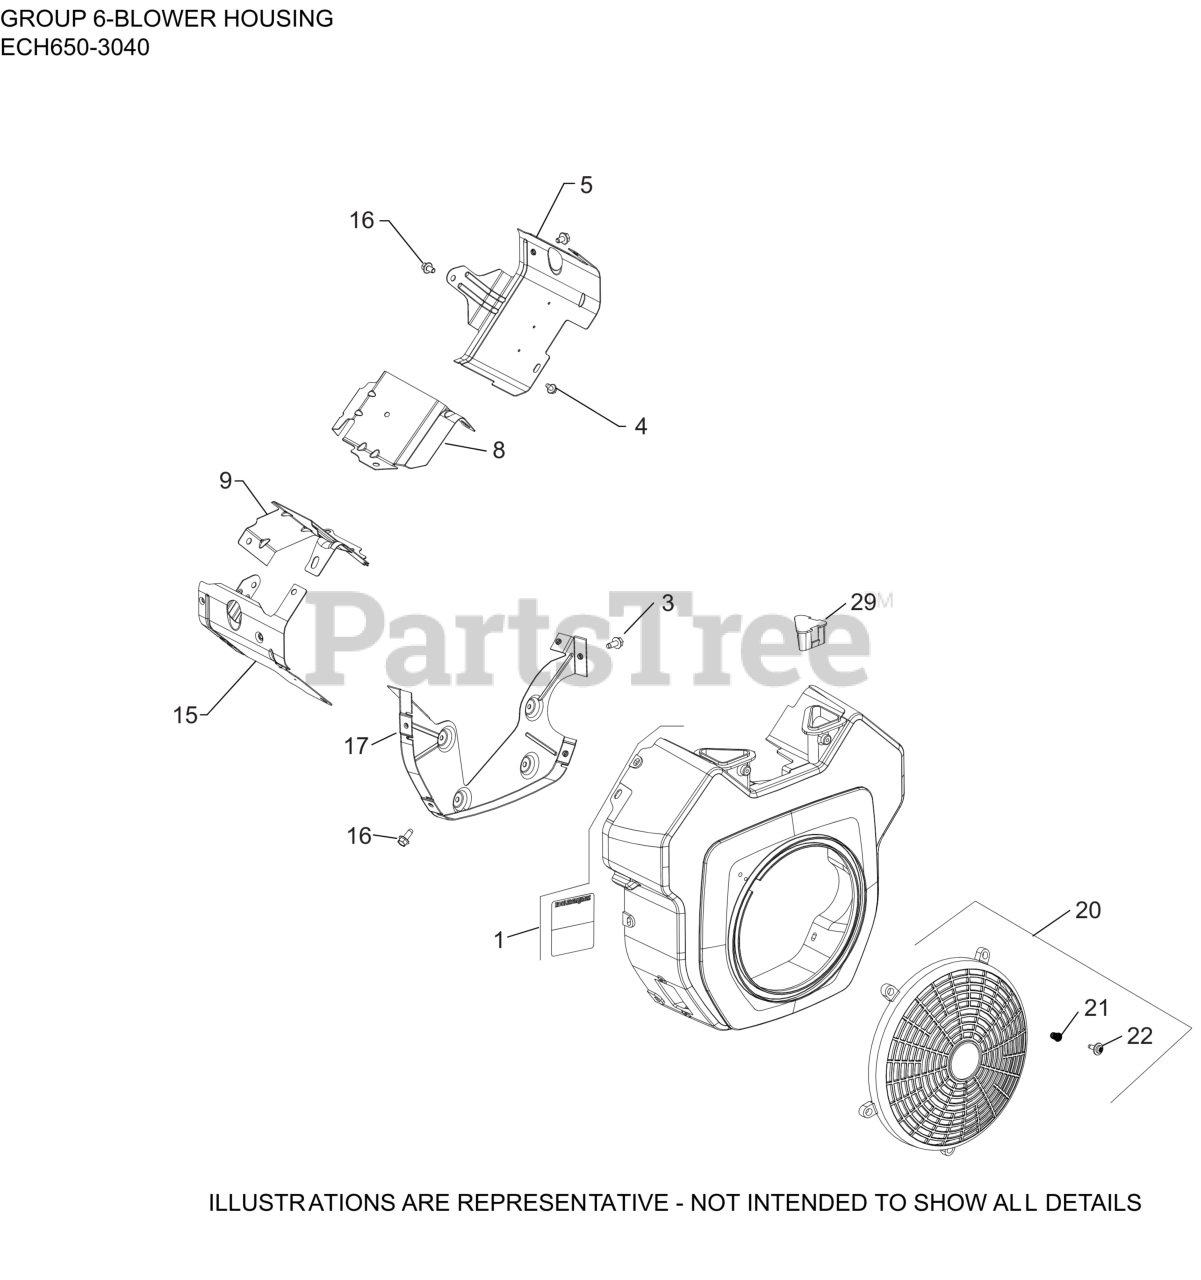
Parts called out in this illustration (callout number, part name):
1	KIT, BLOWER HOUSING
1	HOUSING, BLOWER
3	SCREW, THREAD FORMING
4	SCREW, THREAD FORMING
5	KIT, RIGHT BARREL
8	BAFFLE, VALLEY #1 CYLINDER
9	BAFFLE, VALLEY #2 CYLINDER
15	BAFFLE LEFT BARREL
16	SCREW, THREAD FORMING
17	PLATE, BACKING
17	KIT, BACKING PLATE
20	KIT, FIXED GUARD
21	INSERT, THREADED (M5)
22	SCREW, SEMS
29	COVER, BLOWER HOUSING
